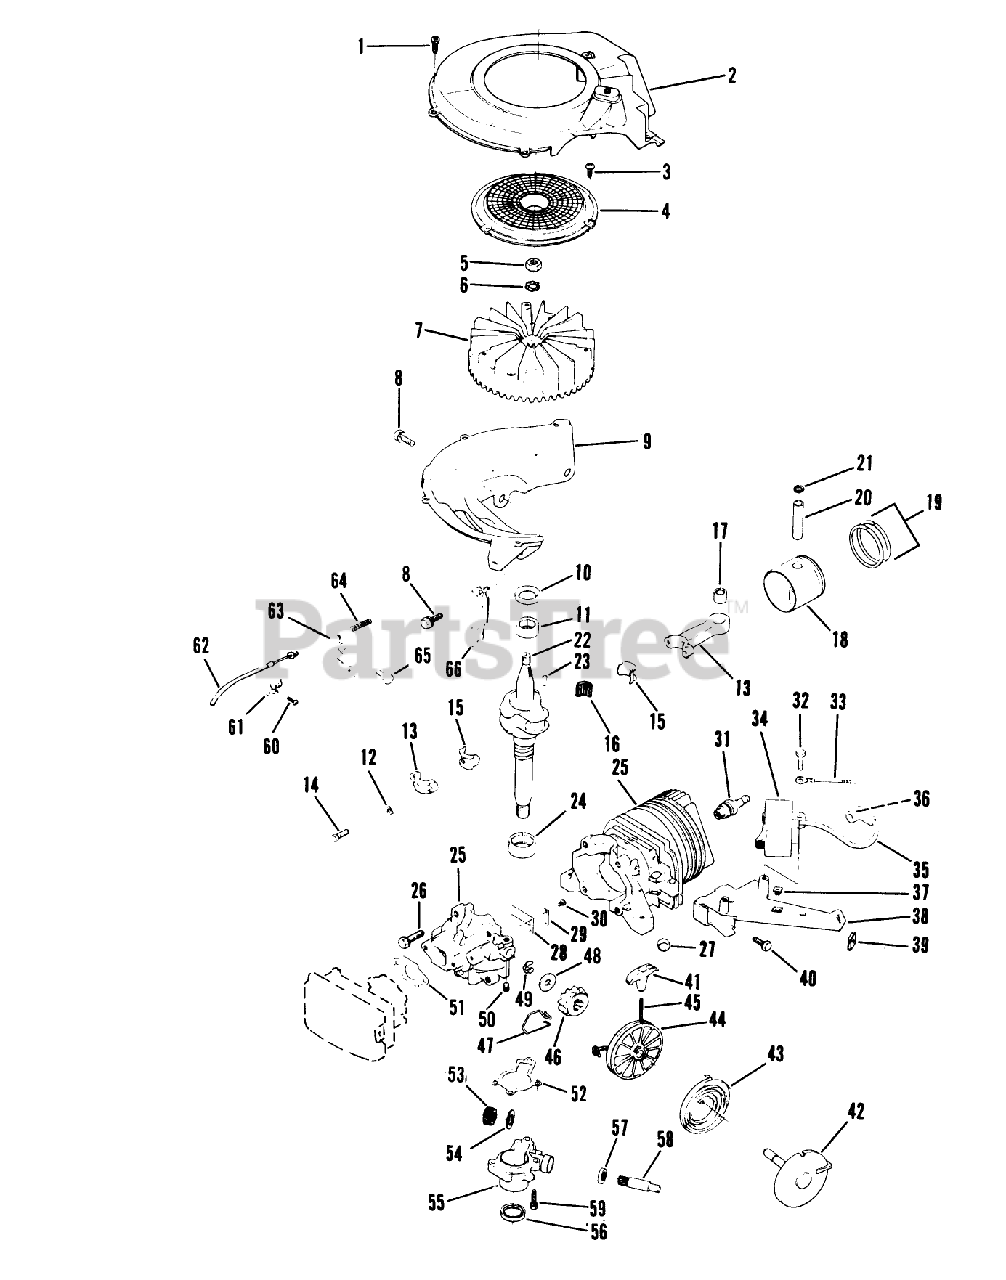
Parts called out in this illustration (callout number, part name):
1	SCREW S
2	AIR BAF&EYELET S
3	SCREW F
5	NUT
8	SCREW-SEMS
9	SHROUD BASE S
11	BEARING V
14	SCREW
15	LINER ASM
17	BEARING AY F
21	RING-RETAINING
23	KEY
24	BEARING S
26	SCREW S
27	PLUG-CORE VF
29	PLATE-BACKUP, REED
35	HT LEAD&COVER XEV
37	NUT-CLIP
39	NUT - SPEED S
41	HANDLE STARTER S
43	SPRING S
47	SPRING F
48	WASHER S
50	SET SCREW
51	GASKET CARB S
52	GASKET S
53	GEAR, DR SHAFT S
54	THRUST WASHER
57	SEAL S
61	CLIP S
63	LEVER LOCKOUT S
65	BOLT S
